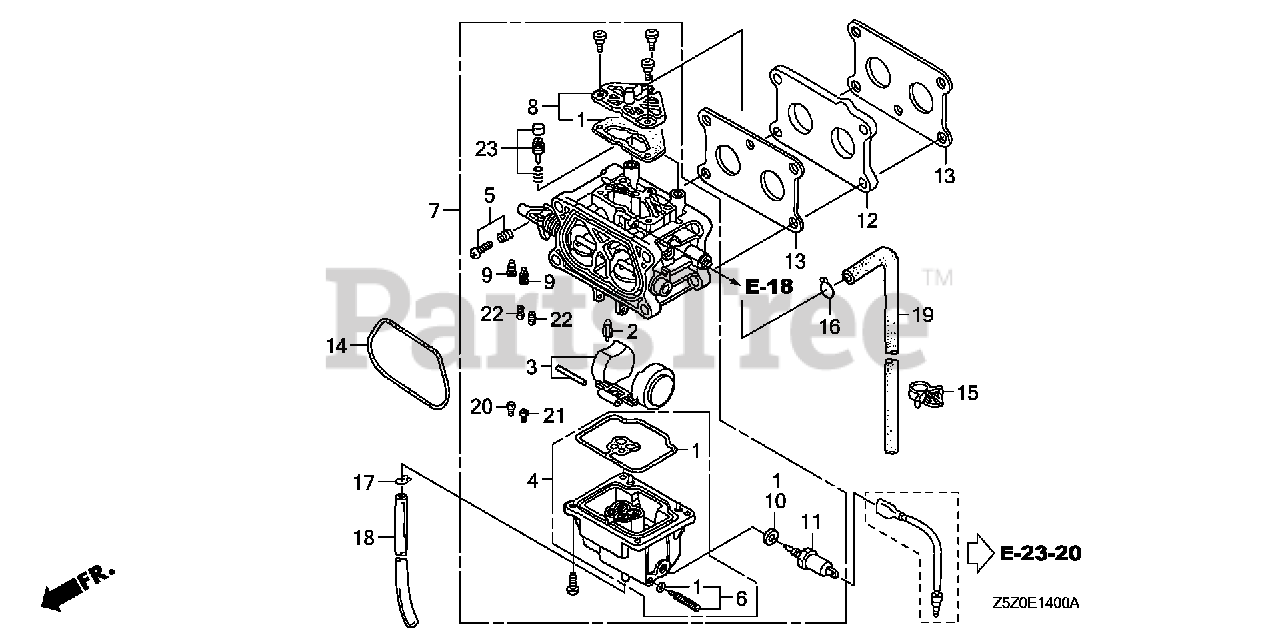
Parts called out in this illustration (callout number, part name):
1	GASKET SET
2	VALVE, FLOAT
4	CHAMBER SET, FLOAT
6	SCREW SET, DRAIN
7	CARBURETOR ASSY. (BW04B C)
8	COVER SET, AIR VENT
11	VALVE ASSY., SOLENOID
12	INSULATOR, CARBURETOR
13	GASKET, INSULATOR
14	GASKET, AIR CLEANER
15	CLIP, WIRE HARNESS
16	CLIP, TUBE (B8)
17	CLIP, TUBE (B6.5)
18	BULK HOSE, VINYL (4X7X8000) (4X7X300)
19	BULK HOSE, VACUUM (4.5X1000) (4.5X400)
20	JET, MAIN (#71.3)
20	JET, MAIN (#73.8)
20	JET, MAIN (#76.3)
21	JET, MAIN (#73.8)
21	JET, MAIN (#76.3)
21	JET, MAIN (#78.8)
22	JET, PILOT (#35)
23	SCREW SET, PILOT
